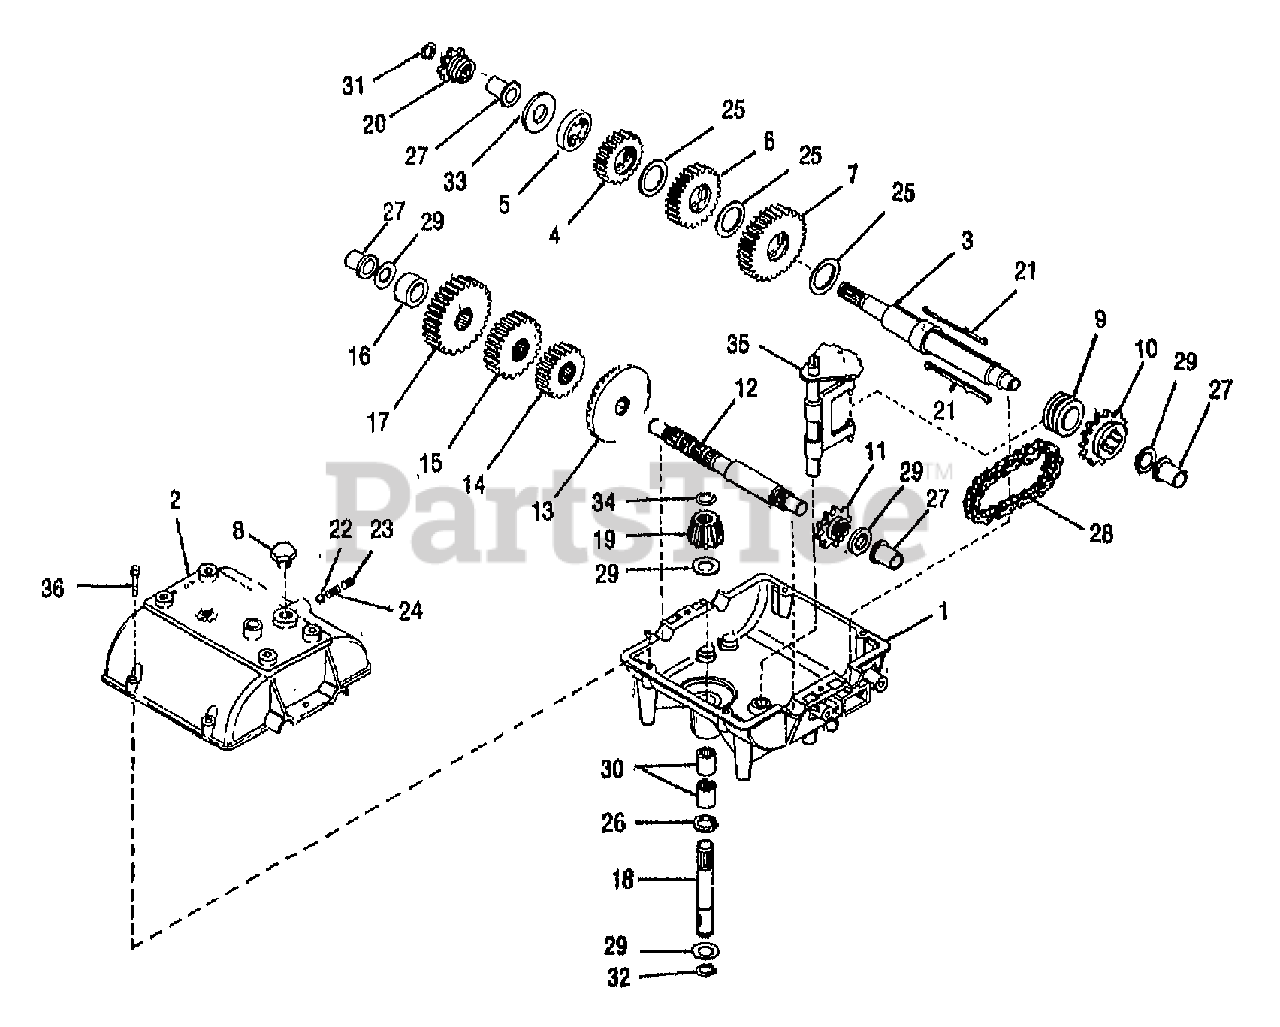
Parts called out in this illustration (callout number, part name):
1	TRANSMISSION CASE
3	OUTPUT SHAFT
4	SPUR GEAR
6	SPUR GEAR
7	SPUR GEAR
10	SPROCKET
11	SPROCKET
12	COUNTERSHAFT
13	BEVEL GEAR
14	SPUR GEAR
15	SPUR GEAR
17	SPUR GEAR
18	INPUT SHAFT
19	INPUT PINION
20	SPROCKET
21	SHIFT KEY
24	SPRING
25	WASHER
26	O RING
27	BUSHING
28	ROLLER CHAIN
29	WASHER
30	NEEDLE BEARING
31	RET RING
32	RET RING
34	RET RING
35	ROD & FORK
